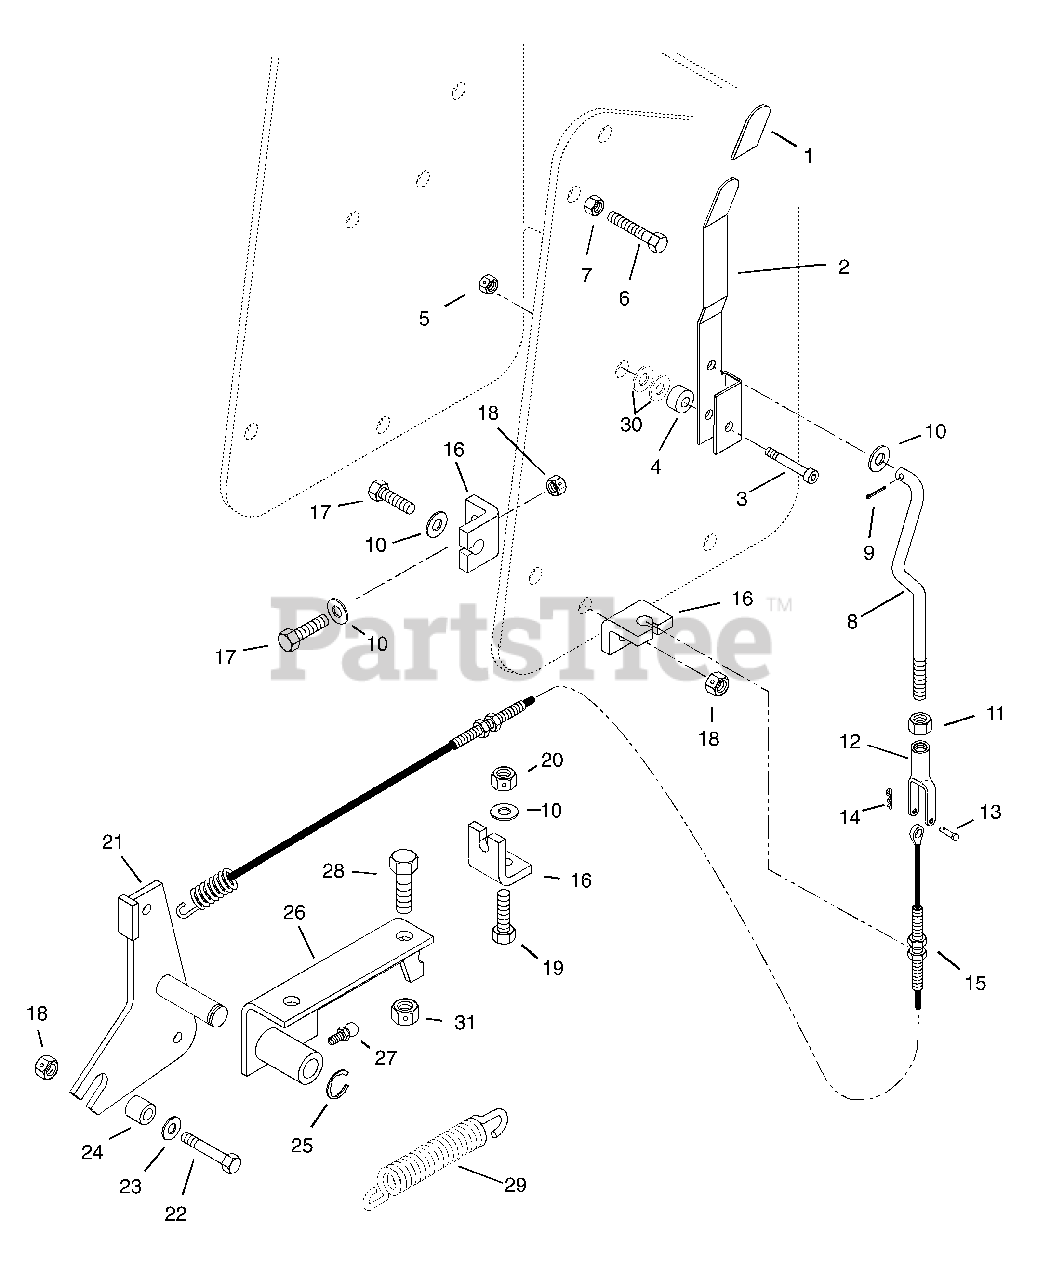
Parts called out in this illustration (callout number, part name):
1	Grip-Handle
2	Lever-Brake
3	Shoulder Bolt .38-16X1.25
5	Nut-Locking-Center .31-18
6	Bolt-Hex .25-20 x 1.5 Grade 5
7	Nut-Hex .25-20
8	Rod-Brake Link
9	Pin-Cotter .12 x .75
10	Washer-Flat-Steel .344 X .688 X 1.25
11	Nut-Jam .31-24
12	Yoke .312-24 X 2.25
13	Pin-Clevis .31 X .937
14	Pin-Hair Internal .08 x .18 x 1.18
15	Cable-Brake
16	Bracket-Cable
17	Bolt-Hex .25-20 x 1.00 Grade 5
18	Nut-Locking-Center .25-20
19	Bolt-Hex .31-18 x 1.00 Grade 5
20	Nut-Locking-Center .31-18
21	Weldment-Brake Arm
22	Bolt-Hex .25-20 x 1.75 Grade 5
23	Washer-Flat-Steel .281 x .620 x .065
24	Bushing-Sleeve .260 x .500 x .750
25	Ring-Retaining-External .392 x .042
26	Weldment-Brake Pivot
27	Fitting-Lube .25-28 x .256
28	Bolt-Hex .38-16 X 1.00 Grade 5
29	Spring-Tension .093 x .75 x 4.0
30	Washer-Flat-Steel .312 x .734 x .065
31	Nut-Locking-Center .38-16
